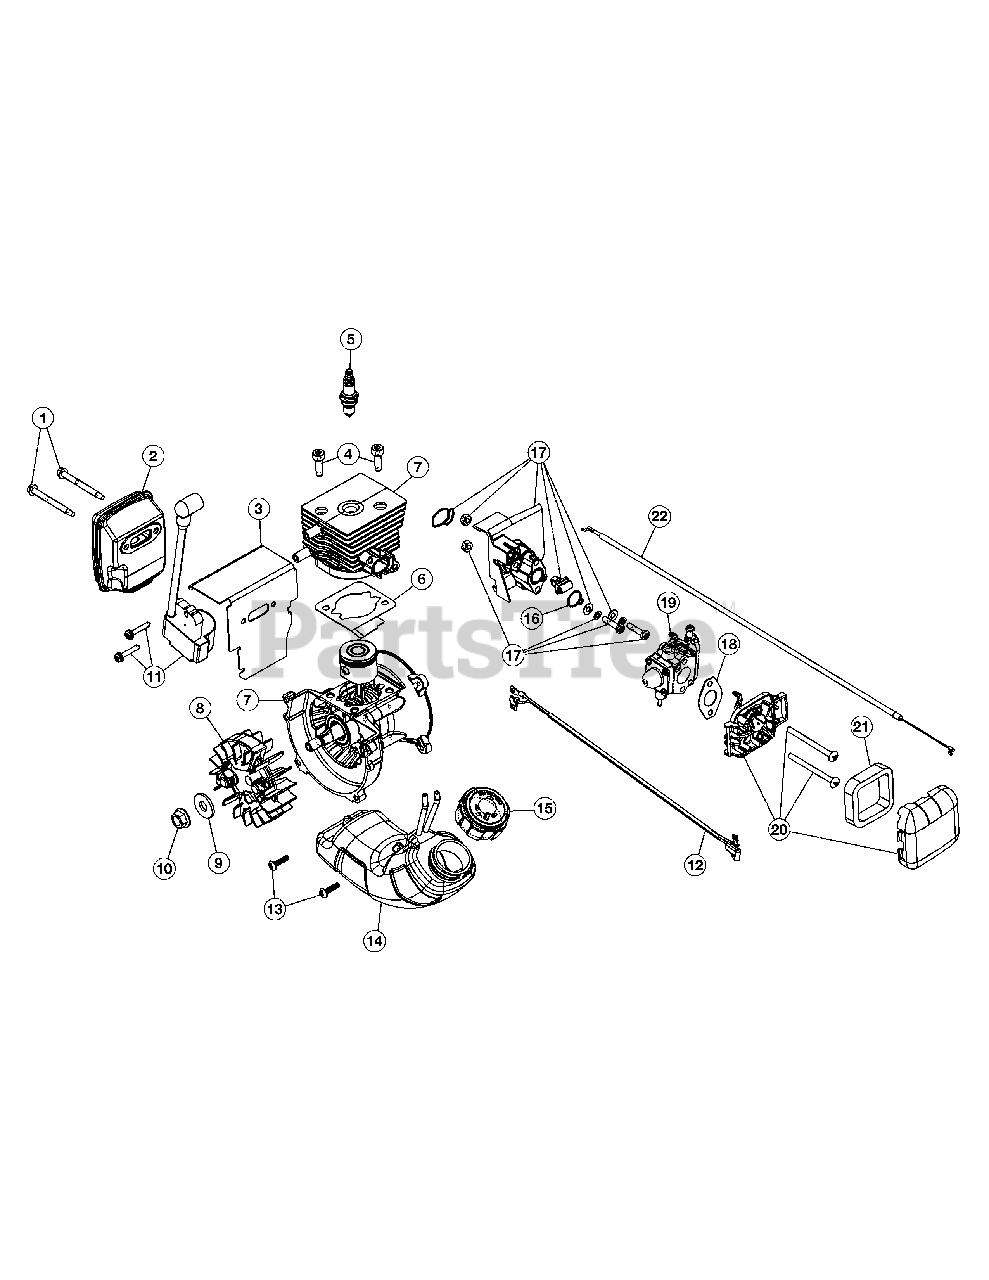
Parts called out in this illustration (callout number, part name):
1	Muffler Screws
2	Muffler Assembly (Incl. 1 & 3)
3	Muffler Gasket
5	Spark Plug
6	Cylinder Gasket
7	Shortblock Assembly (Incl. 4-6 & 8-11)
8	Flywheel Assembly
9	Washer
11	Module Assembly
12	Lead Wire
14	Fuel Tank Assembly (Incl. 13 & 15)
15	Fuel Cap
16	Insulator O-Ring
17	Insulator Assembly (Incl. 16)
18	Carburetor Gasket
19	Carburetor Assembly (Incl. 18)
20	Aircleaner Assembly (Incl. 21)
21	Air Filter
22	Throttle Cable
